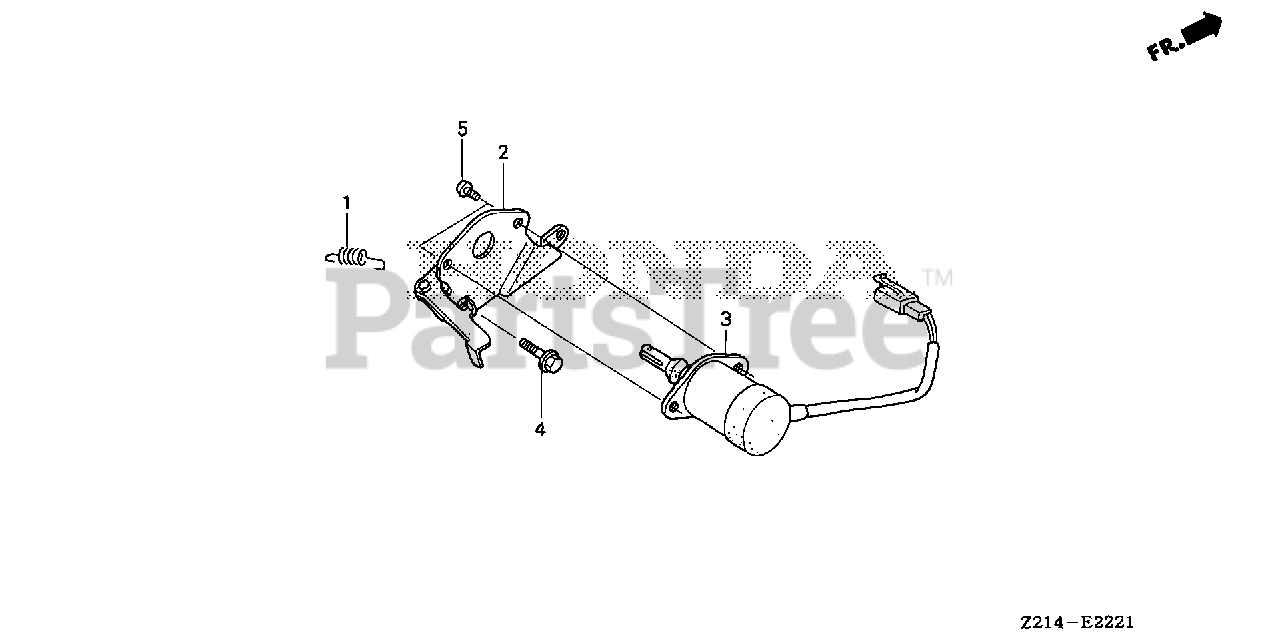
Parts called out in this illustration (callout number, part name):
1	SPRING, CHOKE RETURN
2	LEVER, THROTTLE
3	SOLENOID ASSY.
4	BOLT, FLANGE (6X12) (CT200)
5	SCREW, PAN (5X8)
